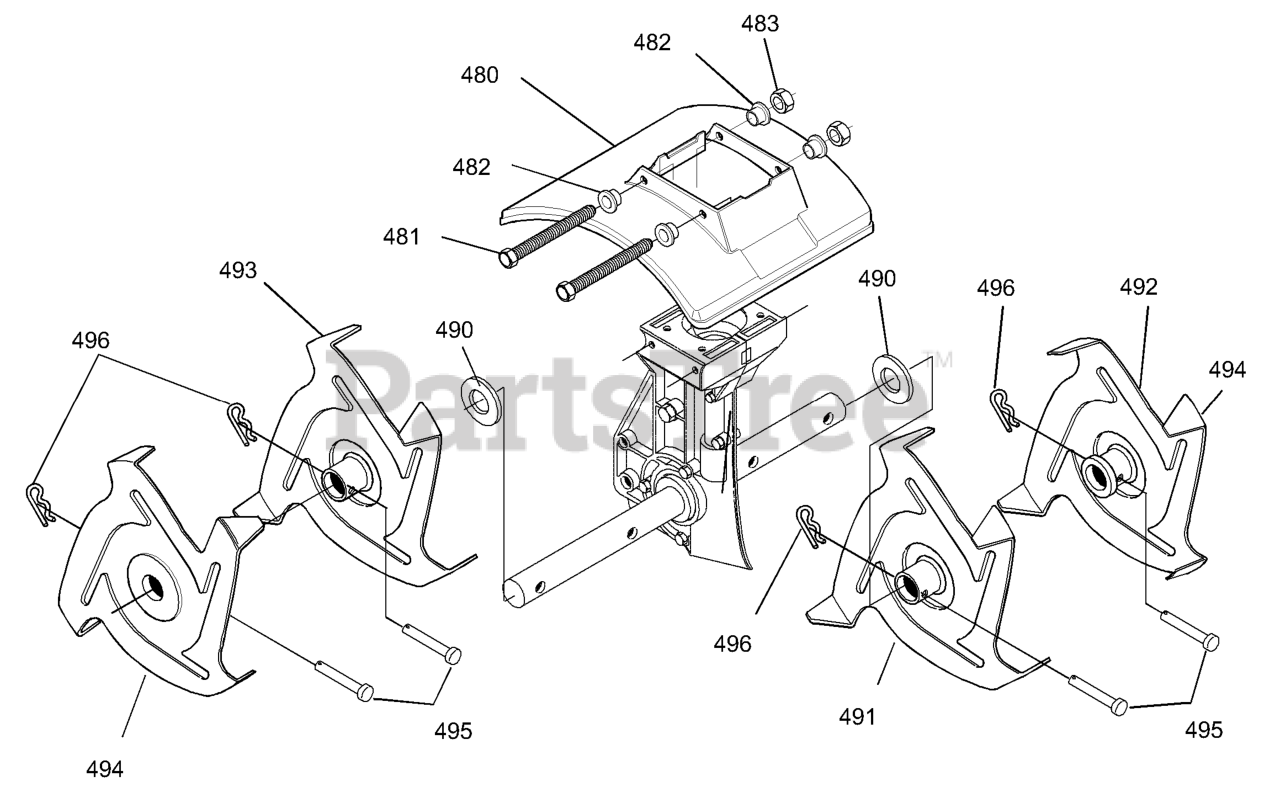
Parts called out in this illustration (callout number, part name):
480	Shield, Tine
481	Screw, 1/4-20x5.50
482	Spacer, Flange
483	Nut, 1/4-20
490	Washer, Felt
491	Tine Assy. Inner LH
492	Tine Assy. Outer LH
493	Tine Assy. Inner RH
494	Tine Assy. Outer RH
495	Clevis Pin
496	Hair Pin
